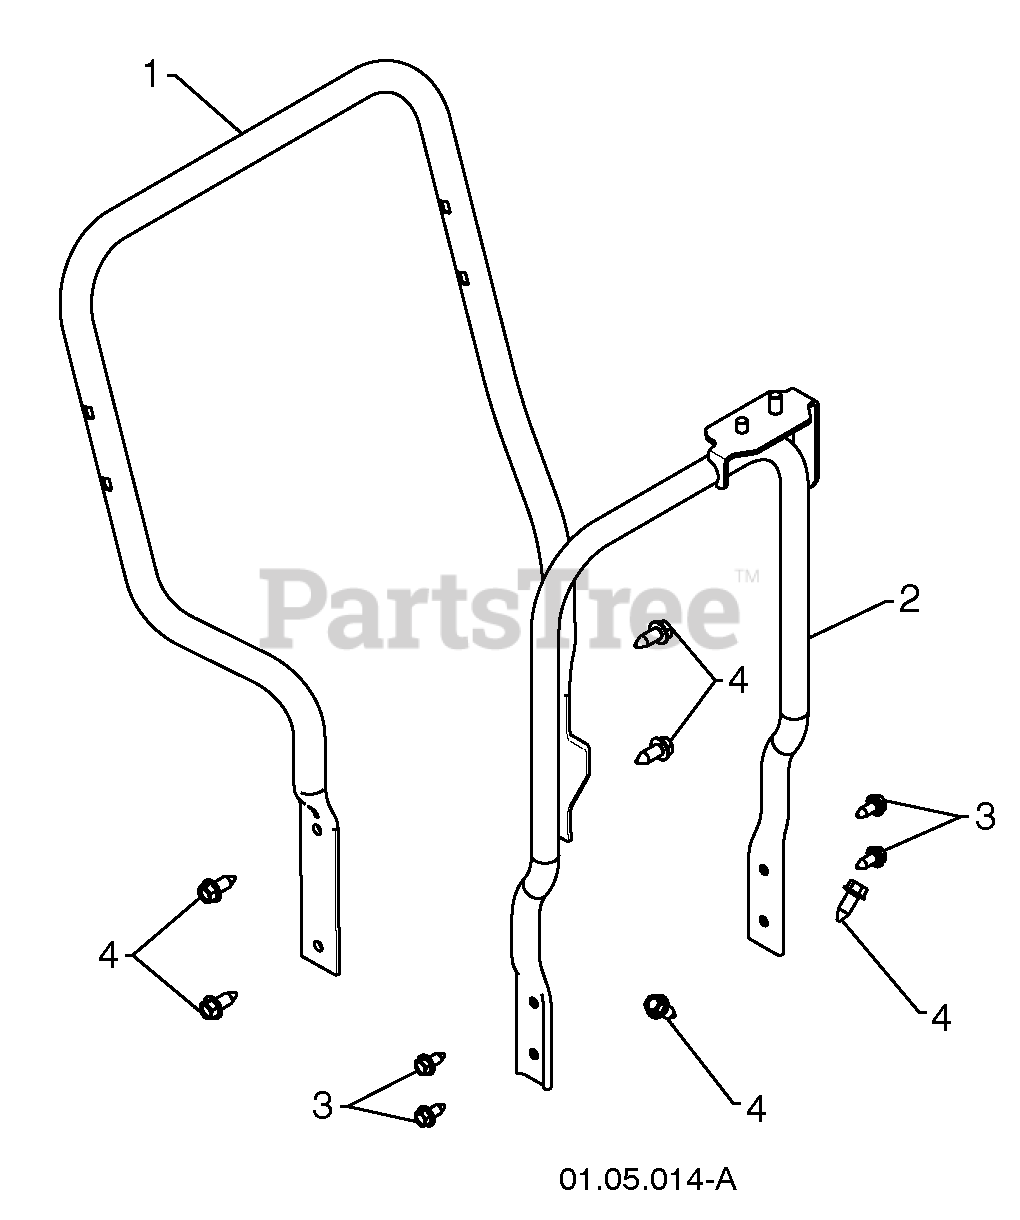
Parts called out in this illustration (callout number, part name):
1	LOWER TUBE GRAY
2	PIVOT SUPPORT
3	BOLT 5/16-18 X .750
4	SCREW 3/8-16 X 1.00
